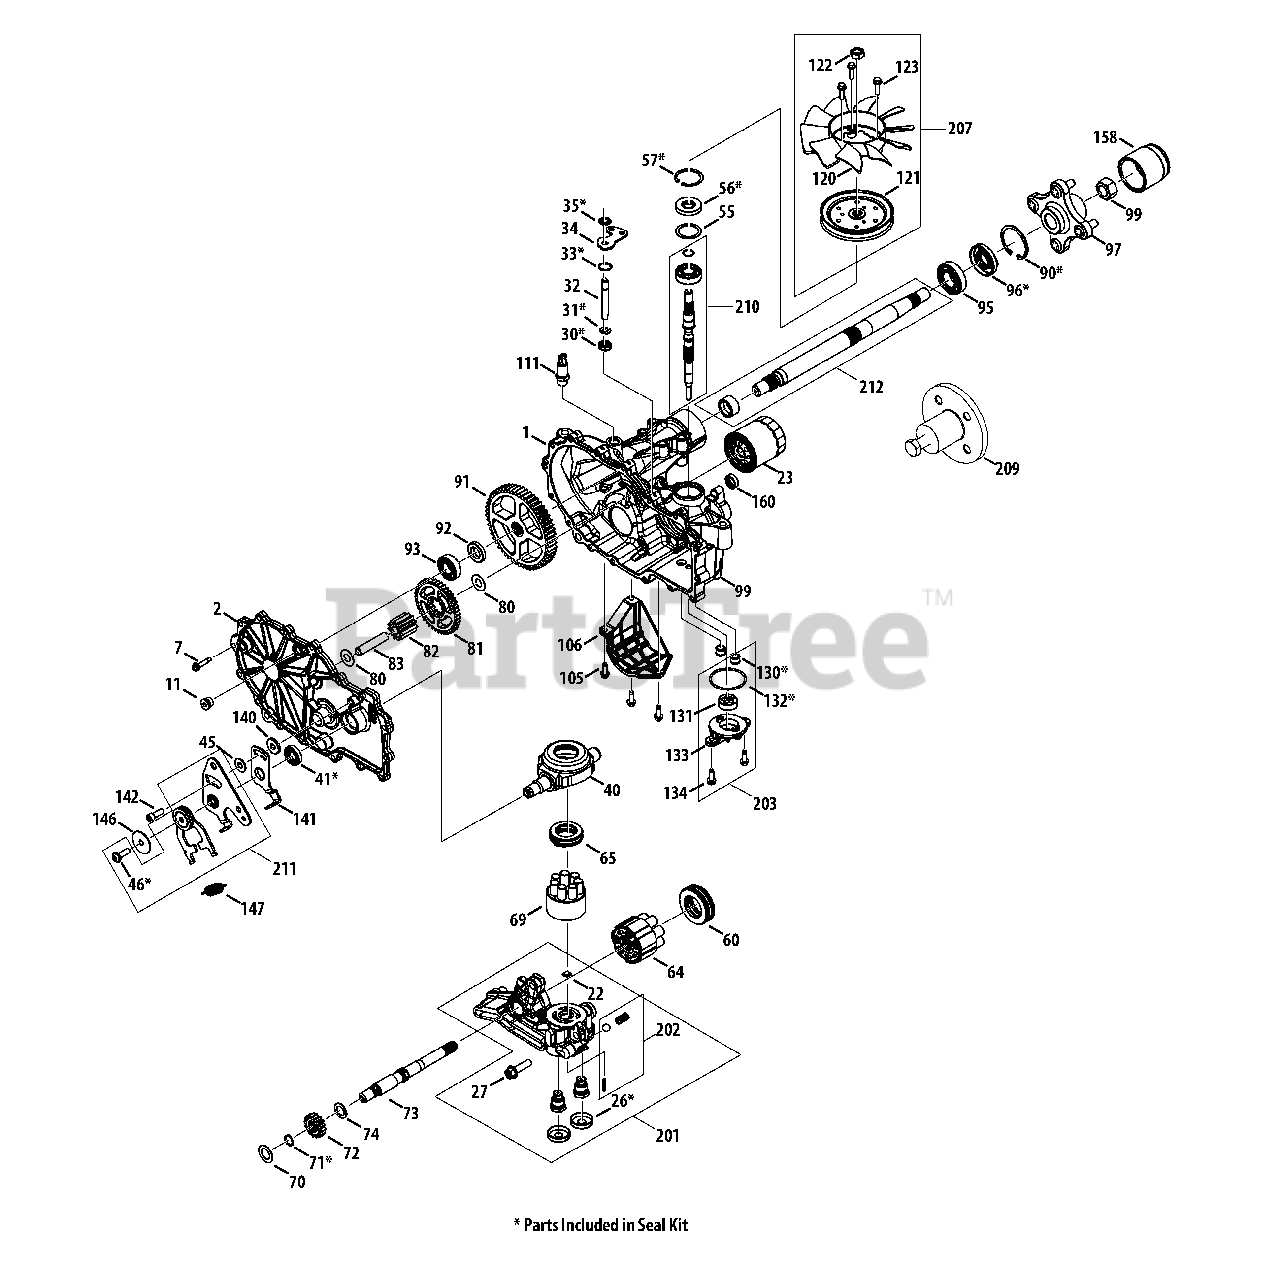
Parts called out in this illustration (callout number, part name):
1	Kit, Housing, Main, LH
2	Kit, Cover, Side, LH
7	Hex Cap Screw, 1/4-20 x 1.125
22	Plate, Bypass
23	Oil Filter
26	Seal, Plug, 1.25 x .25
27	Hex Cap Screw, 3/8-16 x 1.5
30	Seal, Lip .375 x .75 x .25
31	Ring, Ret .375 External
32	Rod, Bypass
33	Ring, Ret .75 Internal
34	Arm, Bypass
35	Ring, Retaining .375 External
40	Trunnion, Swashplate
41	Seal, Lip 12 x 32 x 7
45	Washer, .34 x .88 x .06
46	Hex Cap Screw, 5/16-24 x 1.00
55	Washer, 1.23 x 1.56 x .04
56	Seal, Lip 17 x 40 x 7
57	Ring, Retaining
60	Bearing, Thrust
64	Cylinder Block Assembly
65	Thrust Ball Bearing, 30 x 52 x 13
69	Block 7 Piston Assembly
70	Washer, .63 x 1.0 x .05
71	Retaining Ring, .625
72	Gear, 14t
73	Motor Shaft
74	Washer, .72 x 1.16 x .04
80	Washer, .5 x 1.0 x .03
81	Gear, 45t
82	Gear, 11t
83	Jack Shaft
90	Retaining Ring, 2.06 Internal
91	Gear, 54t
92	Spacer, .75 x 1.32 x .257
93	Ball Bearing, .75 x 40 x 12
95	Ball Bearing, 1.0 x 52 x 15
96	Seal, Lip 25 x 52 x 10
97	Kit, Hub, 4 Bolt
99	Nut, 3/4-16, Hex Lock
105	Hex Cap Screw, 1/4-20 x .75
106	Guard, Filter, LH
111	Fitting, 9/16-18 SAE .5 Barb
120	Fan 7", 10 Blade
121	Disc, Pulley
122	Nut, 1/2-20, Hex Jam
123	Hex Cap Screw, 1/4-20 x .875
130	Connecting Tube
131	Gerotor Assembly
132	O-Ring, -137, .103 x 2.050
133	Charge Pump Cover
134	Hex Cap Screw, 1/4-20 x .75
140	Spacer, .320 x 1.005 x .179
141	Neutral Right Arm
142	Hex Cap Screw, 5/16-24
146	Washer, .343 x 1.5 x .062
147	Extension Spring, .57 x 2"
160	Seal, Lip, .625 x .875 x .25
201	Kit, Center Section, LH
202	Kit, Charge Relief
203	Kit, Charge Pump
207	Kit, Fan & Pulley
209	Hub Puller, 4 Bolt
210	Kit, Input Shaft
211	Kit, RTN, Bidirectional
212	Kit, Shaft, Axle
